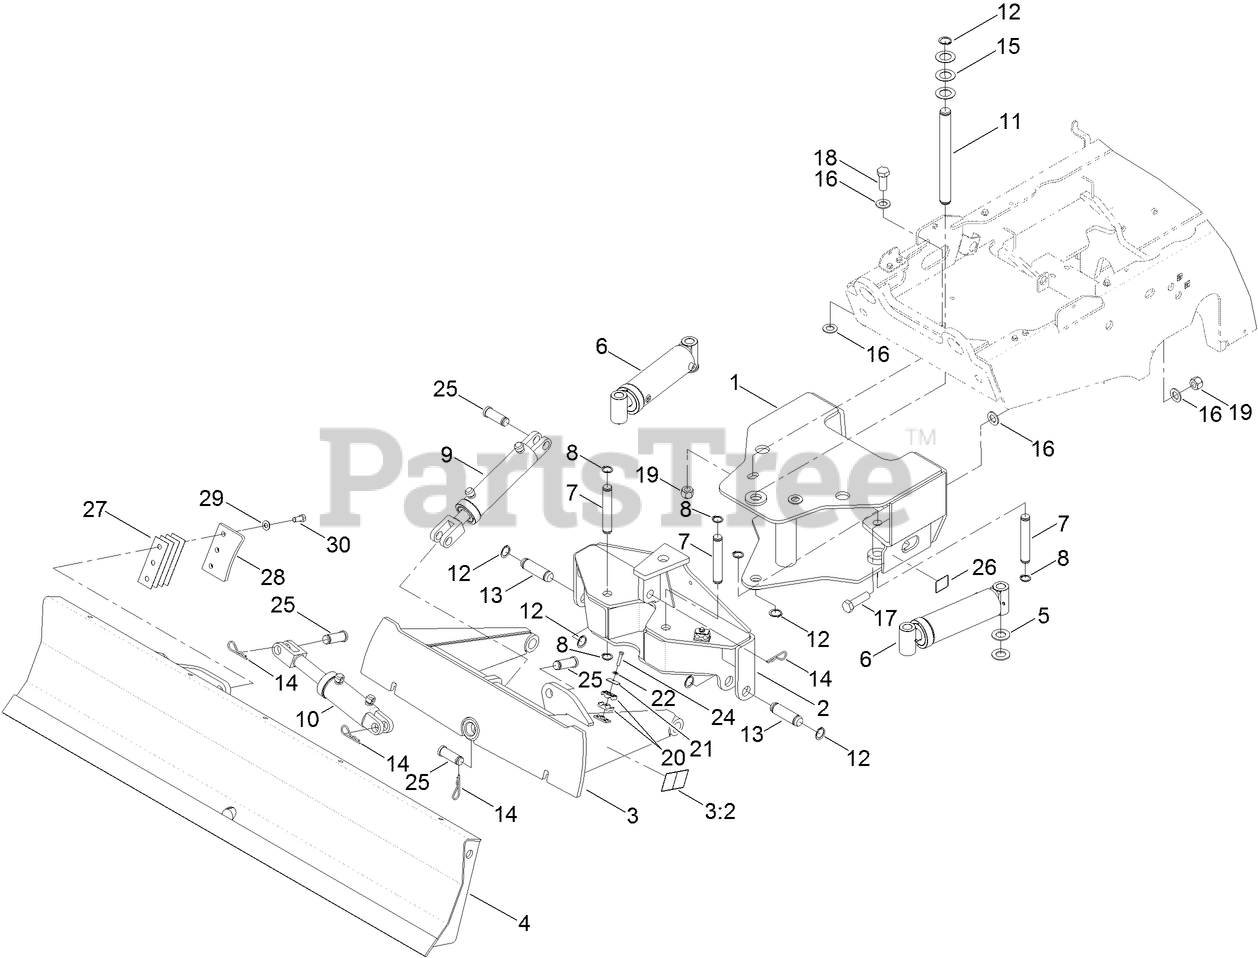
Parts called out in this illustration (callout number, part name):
1	FRAME-BLADE, BACKFILL
2	PIVOT-BLADE, BACKFILL
3	BACKFILL ARM ASM
3:2	DECAL-DANGER
4	BLADE-BACKFILL
5	WASHER-FLAT
6	HYD CYLINDER ASM
7	PIN-ANGLE, CYLINDER
8	RING-RETAINING, EXTERNAL
9	HYD CYLINDER ASM
10	HYD CYLINDER ASM
11	PIN-BLADE
13	PIN-BLADE
14	PIN-COTTER, QUICK ATTACH
17	SCREW-CAP, HH
20	CLAMP-TUBE
21	COVERPLATE
22	WASHER-HARDENED
24	SCREW-HH
25	PIN-CLEVIS
26	DECAL-TIE DOWN
27	SHIM-RETAINER
28	RETAINER-BLADE
29	WASHER-FLAT
30	SCREW-HH
